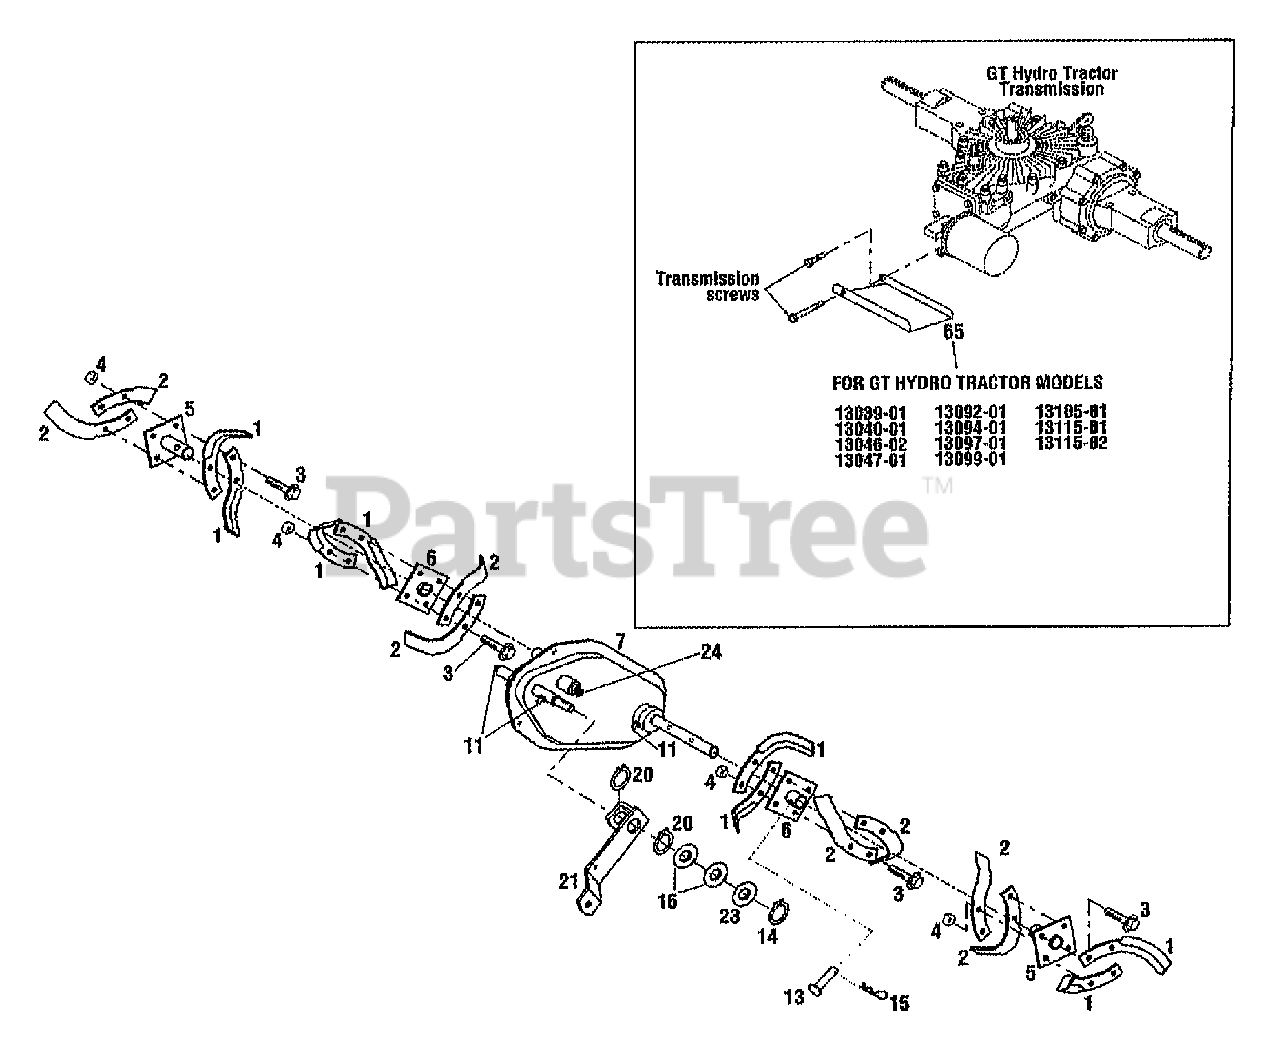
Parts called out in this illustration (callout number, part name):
3	SCR-HH 3/8-16X1.0 G5 ZP
4	NUT-H/LK 3/8-16
5	ASSM-OUTER HUB
6	ASSM-INNER HUB
7	ASSM-TRANSMISSION
11	FITTING-GREASE 1/4-28X2.00
13	PIN-PIVOT
14	RING-HEAVY EXT .625 ID
15	PIN-HITCH
16	WASHER-1.115X.637X.06
20	RING-SNAP
21	ARM-IDLER
23	WASHER
24	FITTING-GREASE 90 DEGREE
